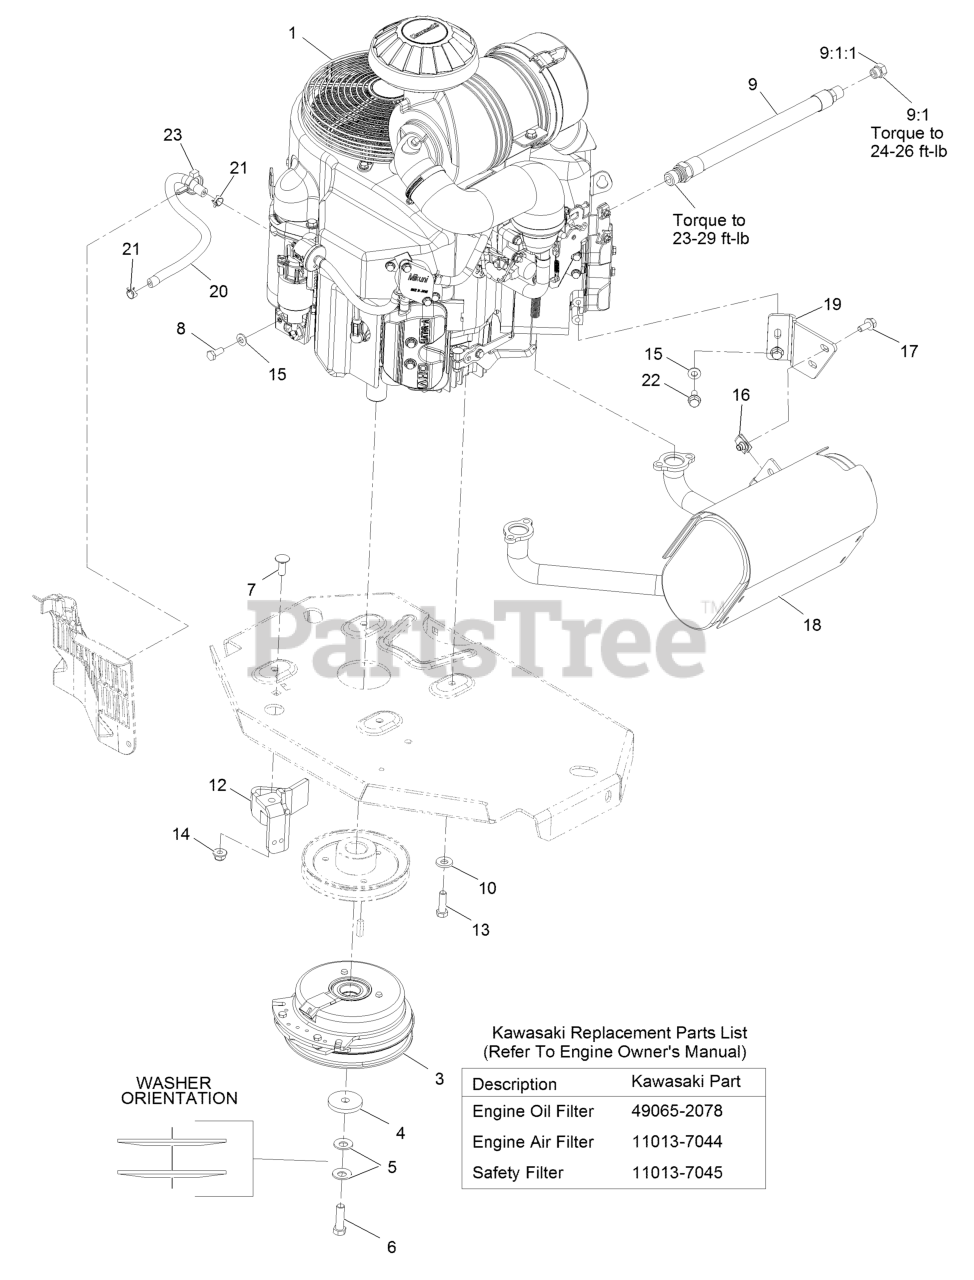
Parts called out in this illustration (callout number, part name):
3	CLUTCH KIT
4	WASHER-CLUTCH
5	WASHER-SPRING
6	SCREW-HH 7/16-20 X 1 1/2 W/LOCTITE
7	SCREW-CARR
8	SCREW-HH
9	ENGINE OIL DRAIN HOSE ASM
9:1	PLUG-HH
9:1:1	O-RING
10	WASHER-BELLEVILLE
12	CLUTCH-ANCHOR
13	SCREW-HH
14	NUT-HF, NI
15	WASHER-SPRING
17	SCREW-HHF
18	MUFFLER
19	BRACKET-MUFFLER
20	HOSE-FUEL
21	CLAMP-HOSE
22	SCREW-HHF
23	CLAMP-HOSE
